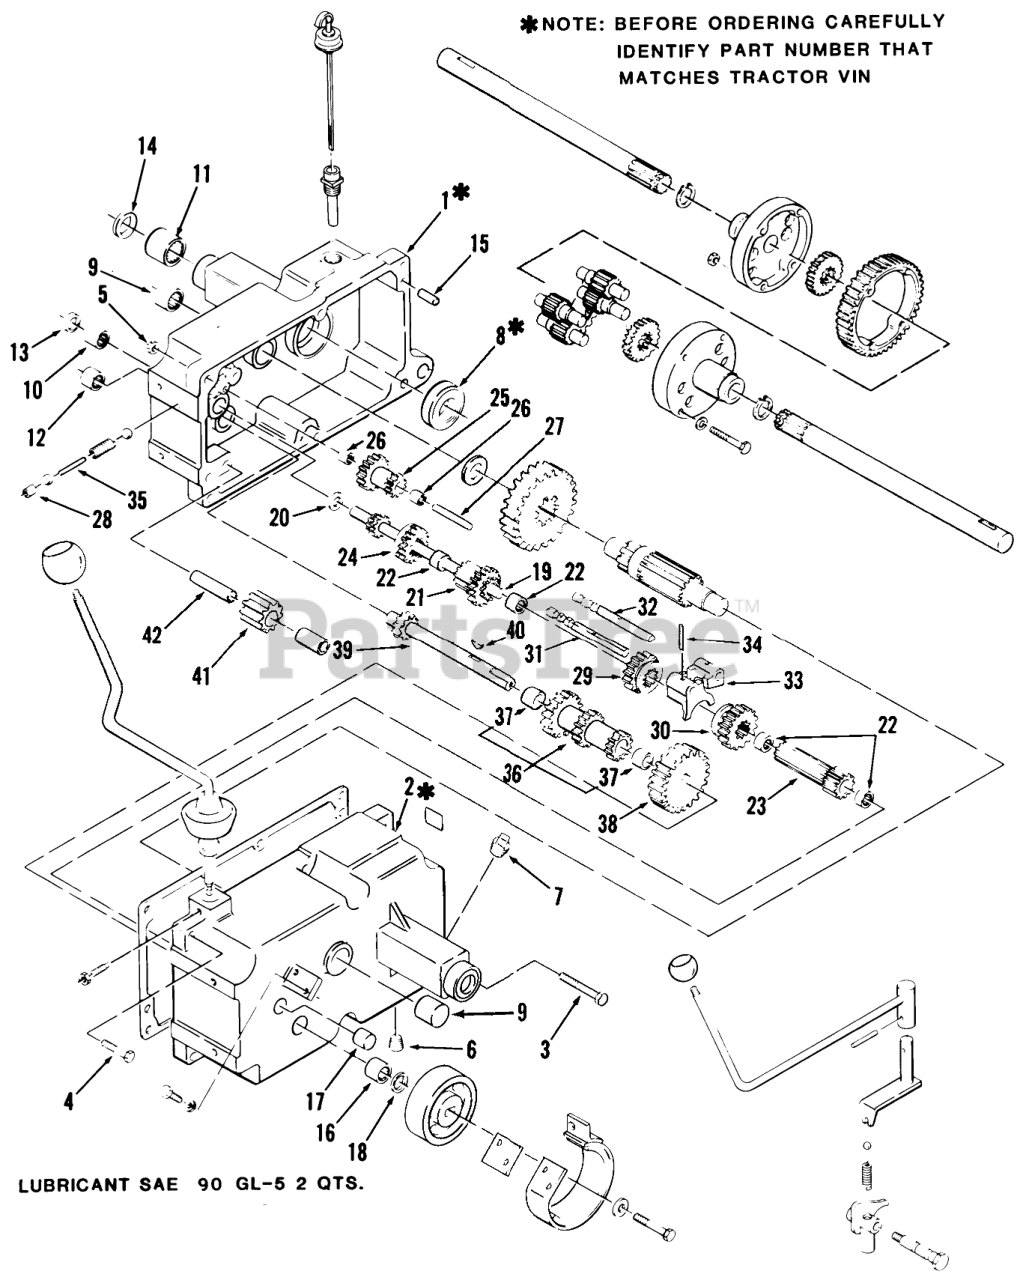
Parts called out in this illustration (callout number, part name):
1	Case-R.H.
2	Case LH.
3	HHCS
4	Bolt
5	Nut
6	PLUG 1/4 PIPE ALLEN
7	Plug
8	BALL BRG 1 1/2 I.D.
9	BEARING-NEEDLE
10	BEARING-NEEDLE
11	BEARING-NEEDLE
12	BEARING-NEEDLE
13	SEAL-OIL
14	OIL SEAL
15	PIN-DOWEL
16	BEARING-NEEDLE
17	Bearing Needle
18	SEAL-OIL
19	SHAFT-INPUT
20	WASHER-THR
21	GEAR
22	BEARING-NEEDLE
23	GEAR
24	GEAR-SLIDING
25	Gear
26	BEARING-NEEDLE
27	GEAR-SHAFT REDUCTION
28	CUP-PLUG
29	GEAR-HI AND 2ND
30	GEAR-LOW AND REVERSE
31	RAIL-SHIFT
32	RAIL-REAR SHIFT
33	FORK-SHIFT
34	PIN-ROLL
35	PIN-SHIFT
36	GEAR-CLUSTER
37	BUSHING-BRONZE
38	GEAR-CLUSTER SHAFT
39	Cluster Shaft
40	KEY-WOODRUFF
41	GEAR/BUSHING ASM-REVERSE IDLER
42	PIN-DIFFERENTIAL
